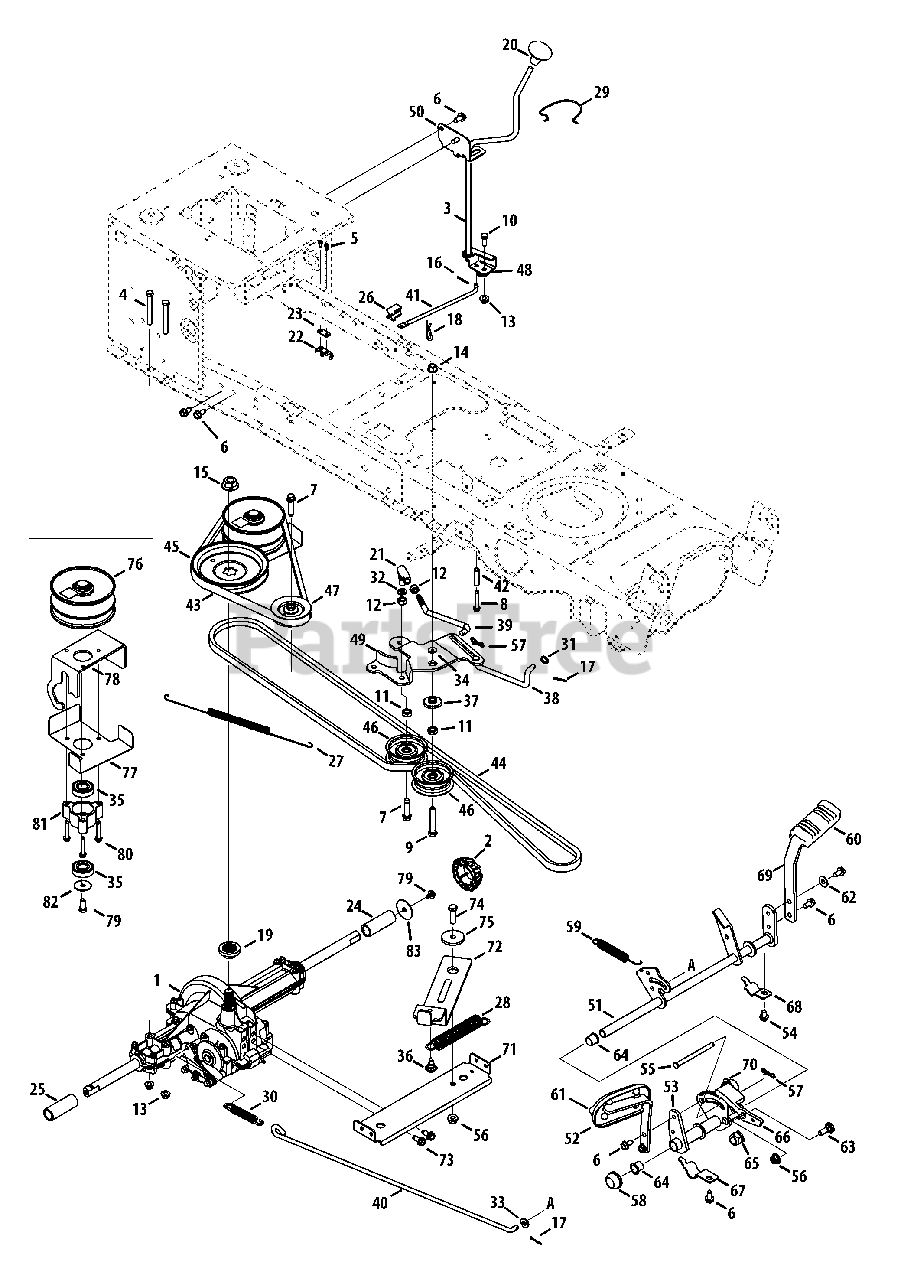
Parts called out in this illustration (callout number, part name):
1	Transaxle Ass’y
2	Cap, Hub
3	Lever Ass’y, Shift
4	Hex Screw, 5/16-18, 2.75, Gr5, Std
5	Screw, Ab, #8-18, 0.500,
6	Screw, Self-tapping, 5/16-18, .750,
7	Screw, Sems, 3/8-16, 1.500
8	Screw, Self-tapping, 1/4-20, 1.750,
9	Hex Screw, 3/8-16, 2.25, Gr5, Std
10	Hex Screw, 5/16-18, .625, Gr5, Std
11	Nut, Jam, 7/16-20, Gr2
12	Nut, Hex, 3/8-24, Gr5
13	Nut, Flange Lock, 5/16-18, Grf
14	Nut, Flange Lock, 3/8-16, Grf
15	Nut, Flange, 9/16-18, Gr2
16	Pin, Cotter, .072 Dia. x 1.13
17	Pin, Cotter, 3/32, 1.0
18	Pin, Cotter Internal, .125 Dia
19	Hub, Pulley, 5/8 Spline
20	Knob, Shift
21	Ball, Joint
22	Switch, Spring, Short
23	Plate, Insulator Nut
24	Sleeve, .758 x .821 x 3.3125
25	Sleeve, .758 x .821 x 2.4375
26	Bearing, Shift Plate
27	Spring, Extension, .70 Dia x 12.00
28	Spring, Extension, .97 OD x 6.18
29	Clip, Spring, Shifter
30	Spring, Extension, .59 OD x 4.00
31	Washer, Flat, .385 x .62 x .063
32	Washer, Lock, 3/8, Regular Duty
33	Washer, Flat, .344 x .750 x .120
34	Wash, Flat, .385 x 1.00 x .03
35	Bearing, Ball, 17x40x12, 6203, Ds
36	Screw, Shoulder, .43x.29, 5/16-18
37	Spacer, Shoulder, 1.375 x .380 x .183
38	Rod, Footpedal Bypass
39	Rod, Adjustment, Idler, 3/8
40	Rod, Brake
41	Rod, Shift,
42	Spacer, .260 x .372 x 1.420
43	Belt, V-Type, Poly
44	Belt, V-Type, Poly
45	Pulley, V-Type, 7.25 Dia Spun
46	Pulley, Idler, Flat 2.75 OD
47	Pulley, Idler, V-Type x 3.06
48	Bracket, Shift, Adjustment
49	Bracket, Idler, Center Double
50	Bracket, Shift, F-N-R
51	Control Ass’y, Brake
52	Ped Ass’y, Control, Auto Drive
53	Bracket Ass’y, Pedal
54	Screw, Self-tapping, 5/16-18, 0.625,
55	Pin, Clevis, 5/16 x 3.985
56	Nut, Flange Lock, 3/8-16, Grf,
57	Pin, Cotter, Bow-Tie 72
58	Cap, Push 5/8
59	Spring, Extension, .63 Dia x 4.95
60	Pad, Pedal, Brake
61	Pad, Control
62	Washer, Bell, .340 x .872 x .060
63	Bolt, Shoulder, .500 x .270, 3/8-16
64	Bearing, Flange
65	Bearing, Hex Flange, .628 ID, Split
66	Latch, Cruise
67	Bracket, Support, Pedal Strap
68	Bracket, Support, Pedal Strap 5/8
69	Bracket, Ped, Brake
70	Plate, Bracket, Reinforcement
71	Bracket Ass’y, Transmission
72	Bracket Ass’y, Idler
73	Screw, Self-tapping, 5/16-18, 0.750,
74	Hex Screw, 3/8-16, 1.25, Gr5, Std
75	Spacer, Shoulder, .8840 x .190
76	Pulley Ass’y, Var Spd, 4.75 OD
77	Keepr Ass’y, Belt
78	Bracket Ass’y, Variable
79	Screw, 5/16-24 x .750
80	Screw, Self-tapping, 1/4-20, 1.500,
81	Cup, Bearing
82	Washer, Flat, .330 x 1.25 x .06,
83	Washer, Flat, .350 x 1.59 x .062
